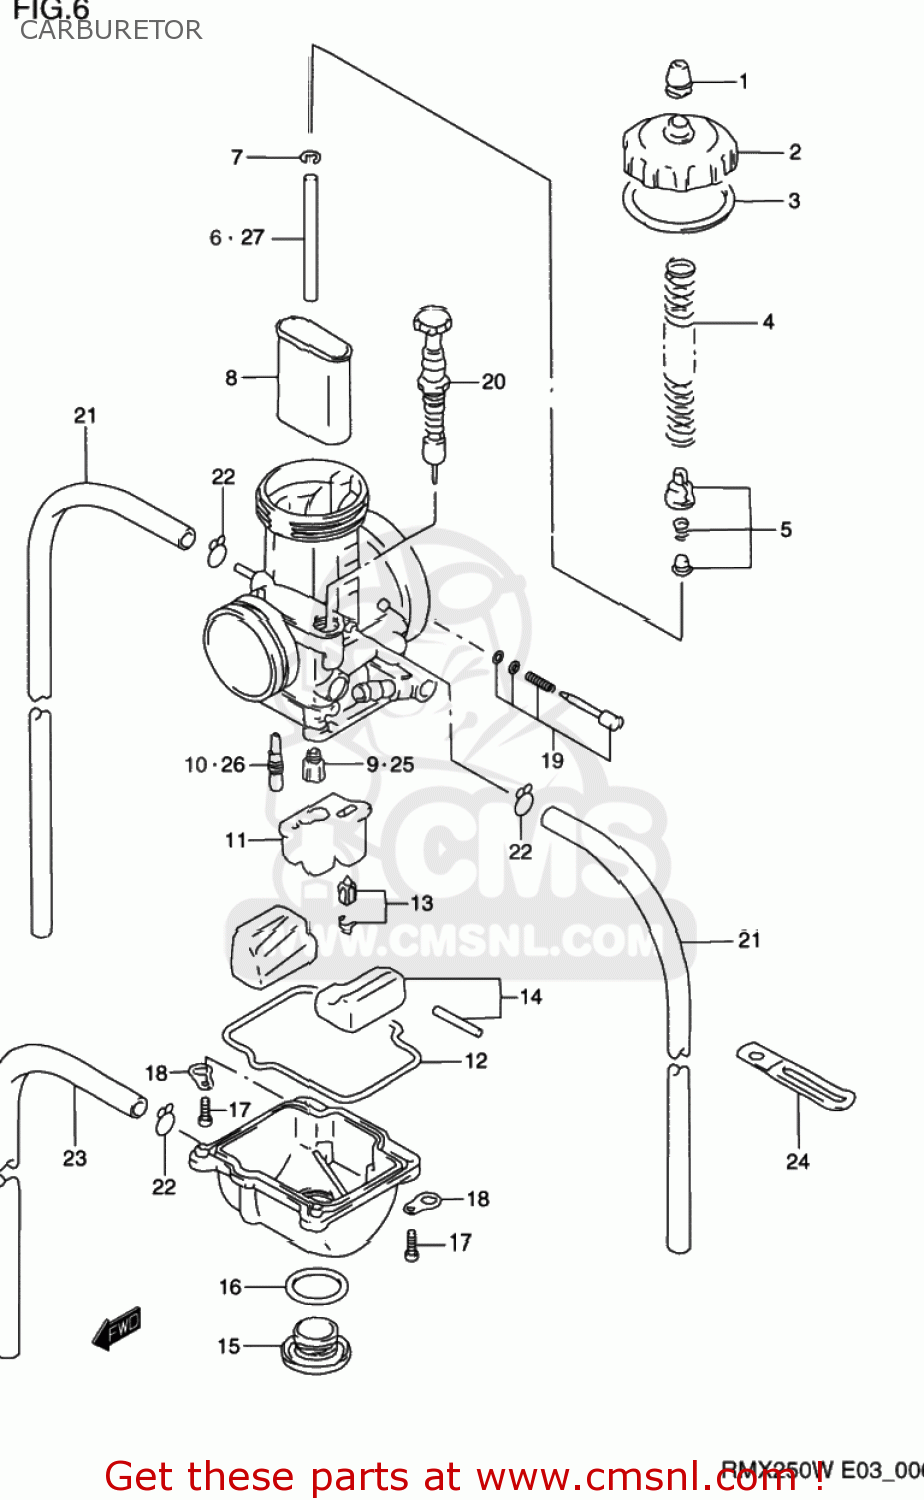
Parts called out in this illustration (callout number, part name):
1	CAP,CARBURETOR
2	CAP,TOP
3	GASKET,TOP CAP
4	SPRING
5	HOLDER SET,CABLE
6	NEEDLE,JET(R1472M 1L)
7	CLIP,NEEDLE
8	VALVE,PISTON(CA:5.0)
9	JET,MAIN(165)
10	JET,SLOW(60)
11	HOLDER
12	GASKET,FLOAT CHAMBER
13	VALVE SET,FLOAT
14	FLOAT SET
15	BOLT,DRAIN
16	O RING
17	SCREW
18	PLATE
19	SCREW SET,AIR
20	PLUNGER ASSY
21	HOSE(4X7X620)
22	CLIP
23	HOSE(3.5X6.5X600)
24	CLAMP(L:45)
25	JET,MAIN(145)
26	JET,SLOW(50)
27	NEEDLE SET,JET
